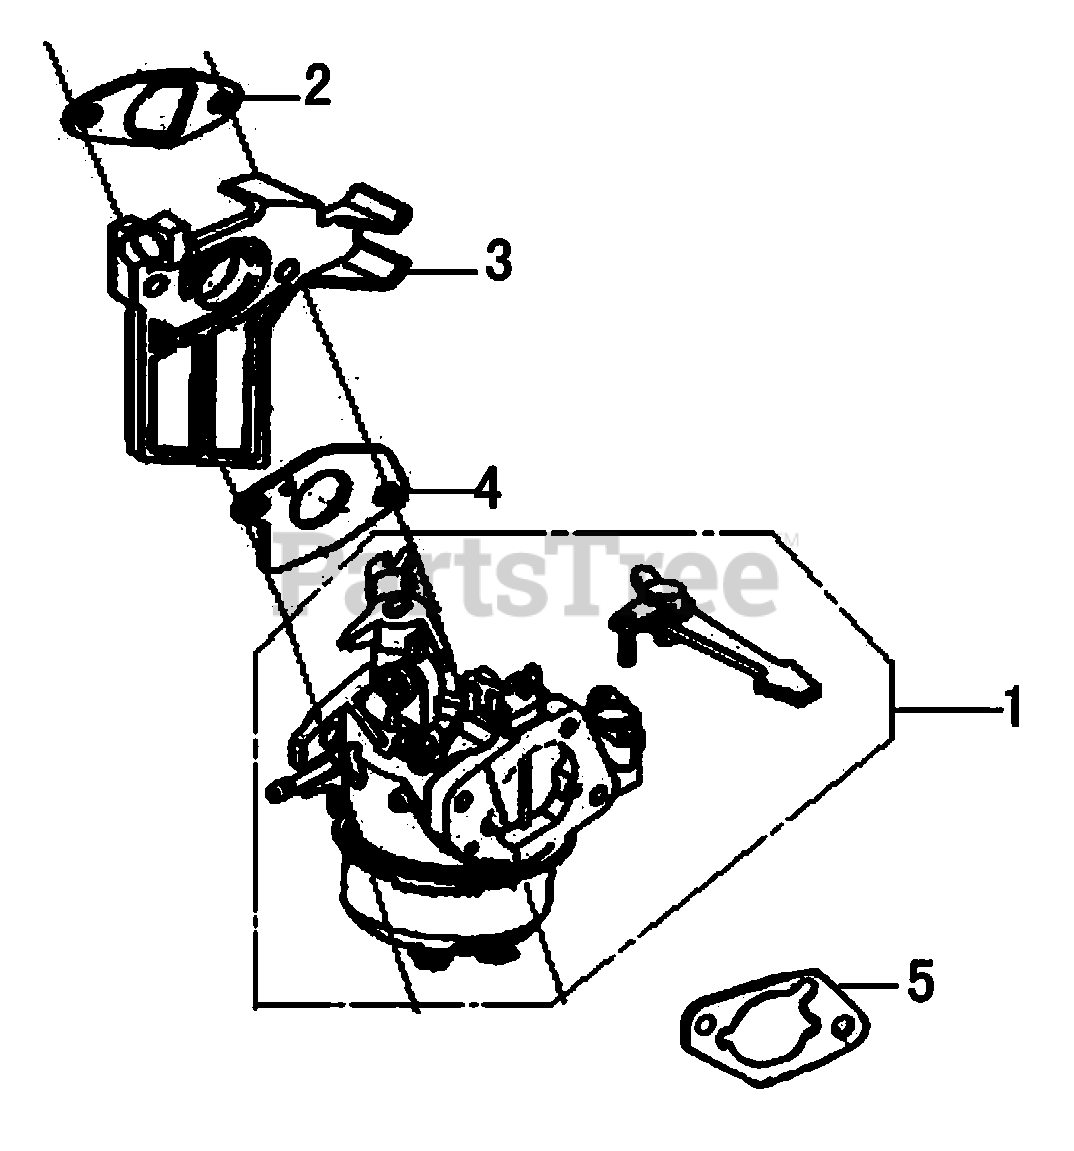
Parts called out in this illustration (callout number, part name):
1	CARBURETOR
2	GASKET, INSULATOR
3	INSULATOR, CARBURETOR
4	GASKET, CARBURETOR
5	GASKET, AIR CLEANER
